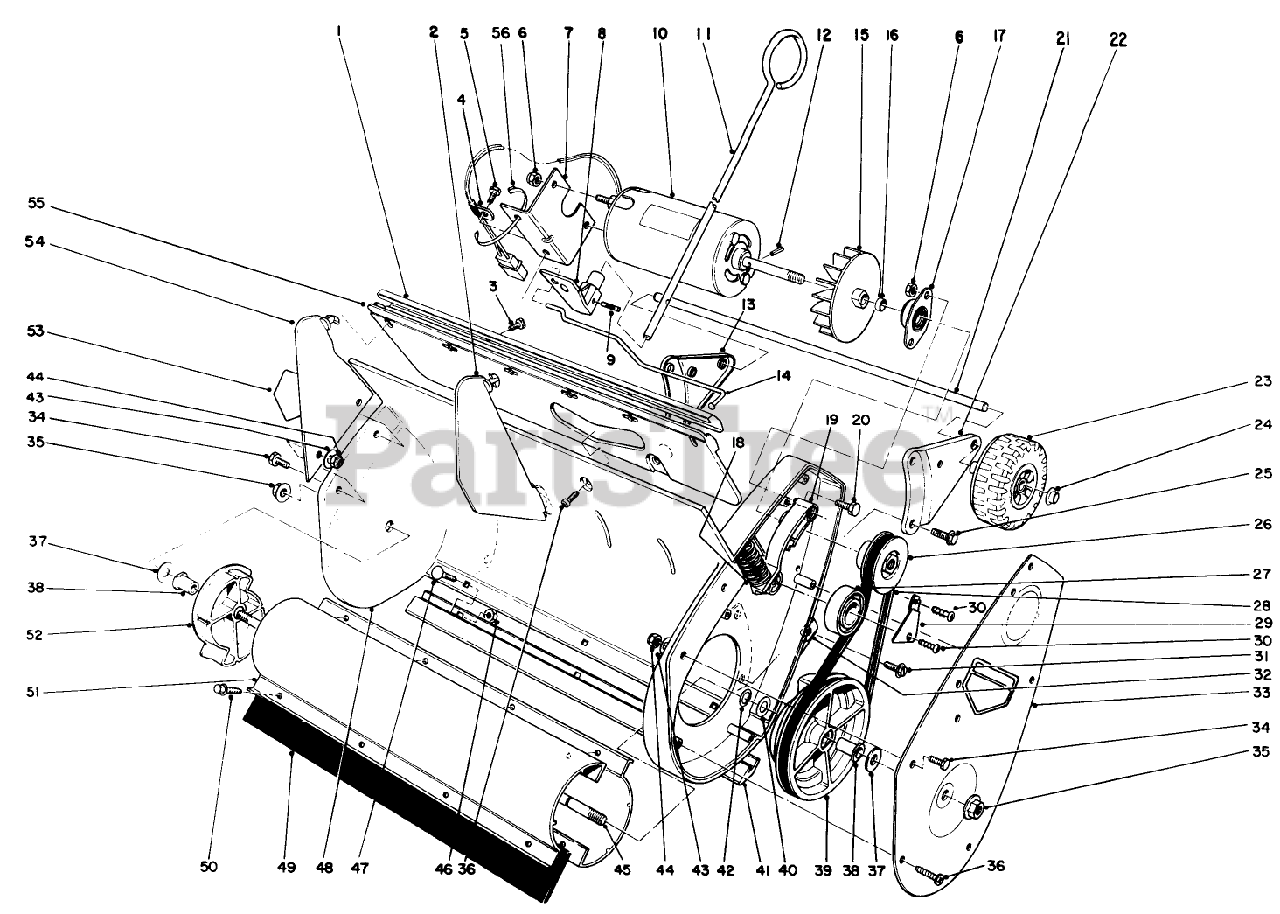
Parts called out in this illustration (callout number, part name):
1	MOULDING
2	INNER VANE
3	10-16 X 3/8 THDG SCREW
4	CLIP-CLOSED, INSULATED
6	NUT-LOCK, NI
7	MOUNTING BRKT B
8	VANE ADJ BRKT
9	GROOVE PIN
10	Motor
11	VANE ADJ ROD
12	SPRING PIN
13	Wheel Bracket R.H.
14	Linkage Vane Adjustment
16	SPACER
17	FLANGED BEARING ASM.
18	IDLER COMP. SPRING
19	IDLER ARM
20	SCREW-HH
21	AXLE SHAFT
22	Wheel Bracket L.H.
23	S-120 WHEEL
24	PUSHNUT-CAP, WASHER
25	Screw
26	DRIVE PULLEY
27	BEARING-BALL
29	IDLER PULLEY RETAINER
30	#8 X .625" PHILPS PAN H
31	SCREW-HWHTF
32	NUT-TYPE J
33	Cover-Belt Case
34	SCREW-HWH
35	NUT-HF
36	Screw
37	THRUST WASHER (THICK)
38	BUSHING ROTOR
39	Pulley-Driven
40	WASHER-THRUST
41	Scraper
42	RING-RETAINING
43	Washer
44	NUT-LOCK, NI
45	ROTOR SHAFT
46	NUT-KEPS
47	SCREW-CARR
48	HOUSING, S-120 HID
49	ROTOR BLADE, S-120 CR
50	TSCREW-HWH
51	ROTOR, S-120 COST REDUC
52	END CAP ROTOR
53	DECAL-DANGER
54	OUTER VANE
55	Vane Mount
56	TIE-CABLE
